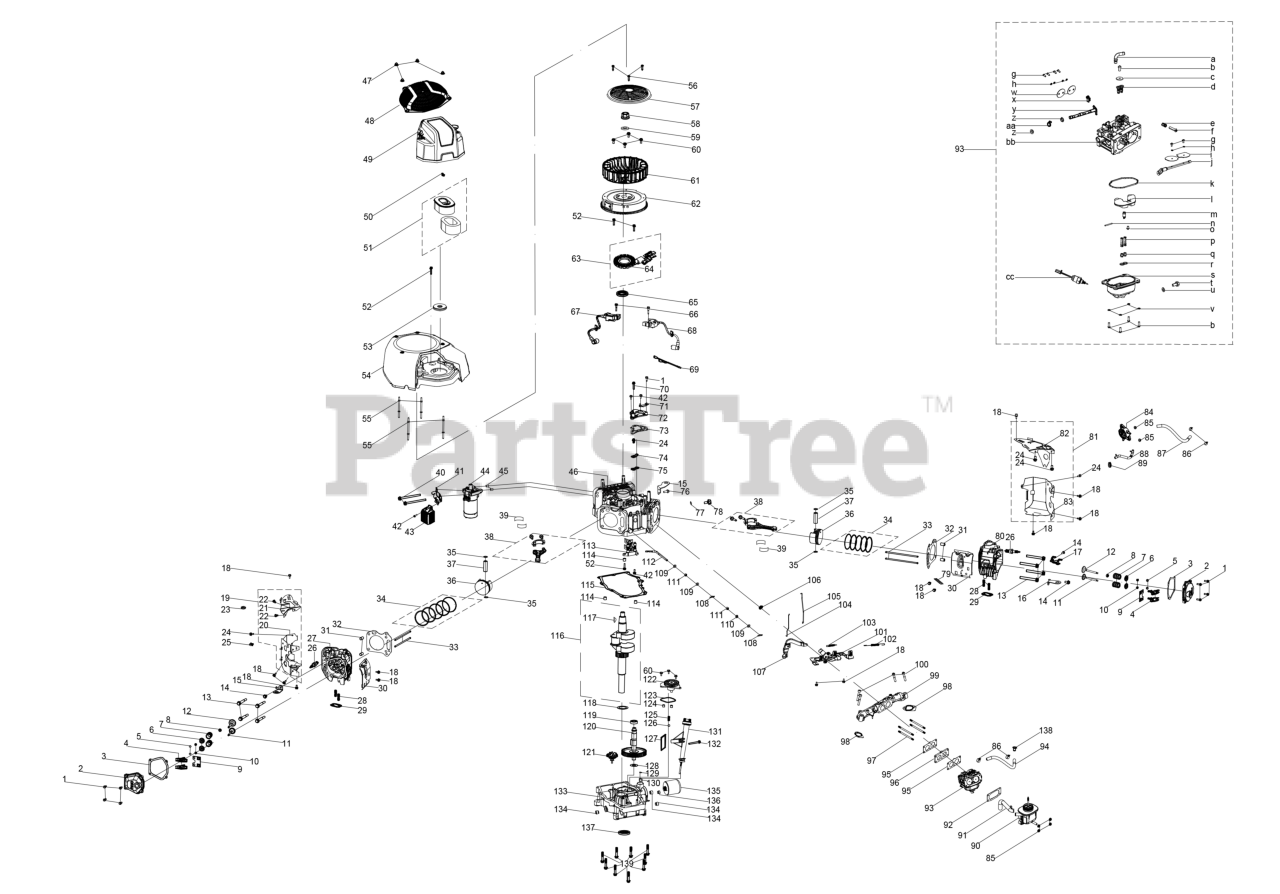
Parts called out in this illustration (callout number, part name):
1	BOLT M6x22
2	VALVE COVER
3	VALVE COVER GASKET
4	ROCKER ARM ASSEMBLY
5	EXHAUST VALVE ADJUSTER
6	VALVE SPRING SEAT
7	VALVE SPRING
8	INTAKE VALVE SEAL
9	PUSH ROD GUIDE
11	EXHAUST VALVE
12	INTAKE VALVE
13	BOLT M10x1.25x87
14	BOLT M8x16
17	MOUNTING BRACKET
18	BOLT M6x12
19	CYLINDER HEAD BAFFLE (LH)
20	CYLINDER HEAD BAFFLE (LH)
21	FLYWHEEL SHROUD (LH)
22	BOLT M6x10
23	HEAT SHIELD GROMMET
24	BOLT M6x10
25	WIRE SUPPORT CLAMP
26	SPARK PLUG (F6RTC/RN11YC/BPR6ES)
27	CYLINDER HEAD (LH)
28	STUD M8 X 34
29	EXHAUST GASKET
31	DOWEL PIN 12x20
32	CYLINDER HEAD GASKET
34	PISTON RIN SET
35	PISTON PIN SNAP RING
36	PISTON ASSEMBLY
37	PISTON PIN
38	CONNECTING ROD
39	CONNETING ROS BEARING
40	BOLT M8x10
41	STARTER RELAY SUPPORT BRACKET
42	BOLT M6x16
44	ELECTRIC STARTER
47	ACORN NUT M6-1
48	SHROUD FAN COVER
49	AIR FILTER COVER ASSEMBLY
50	WING NUT M10
51	AIR FILTER ELEMENT
52	BOLT M6x25
54	BLOWER HOUSING
56	SELF TAPPING BOLT 5.5x25
57	DEBRIS SHIELD
58	NUT M20x1.5
59	WASHER 20.5 x 5 x 40
60	BOLT M6-1 x 18
61	COOLING FAN
63	CHARGING COIL
64	CHARGING COIL
65	OIL SEAL 38 x 58 x 8
66	BOLT M6x30
67	IGNITION MODULE (LH)
68	IGNITION MODULE (RH)
69	CARB HARNESS
70	BOLT M6 X 28
71	FLYWHEEL OUTLET SHIELD
72	BEATHER COVER
73	BREATHER COVER GASKET
74	BREATHER REED BRACKET
75	BREATHER REED ASSEMBLY
76	BOLT M8x20
77	WASHER 20.5X1.5X18
78	BOLT M10x1x10
80	CYLINDER HEAD (RH)
81	CYLINDER SHROUD (RH)
82	COMBINATION GUARD (RH)
83	CYLINDER HEAD BAFFLE (RH)
86	CARBURETOR HOSE CLAMP
90	AIR FILTER BASE
91	BREATHER HOSE
92	AIR FILTER HOUSING GASKET
93	CARBURETOR
94	FUEL LINE 6.3 x 12.5 x 470
95	CARBURETOR GASKET
97	STUD M6-1 X 105
98	INTAKE MANIFOLD GASKET 9Q78
99	INTAKE MANIFOLD
100	BOLT M8x50
101	GOVERNOR GEAR BRACKET
102	GOVERNOR SPRING
103	GOVERNOR SPRING
104	CHOKE LEVER
105	THROTTLE LINKAGE
106	CHOKE LINKAGE LOCK CLAMP
107	GOVERNOR LEVER
108	GOVERNOR SHAFT CLIP
109	FLAT WASHER 8.5X15.8X2
110	GOVERNOR SEAL
111	NEEDLE BEARING 8X12X10
112	GOVERNOR ARM ROD
113	ROCKER ARM ASSMBLY (LOWER)
115	CRANKCASE GASKET
116	CRANKSHAFT ASSEMBLY
117	WOODRUFF KEY
118	WASHER - 38.5X1.0X54
119	CAMSHAFT BEARING
120	CAMSHAFT ASSEMBLY
121	GOVERNOR GEAR
122	OIL PUMP ASSEMBLY
123	OIL PUMP GASKET
125	OIL PUMP SPRING
126	STEEL BALL M9.5
127	OIL PUMP SCREEN
128	THRUST WASHER 17.4X25.9X1.0
129	O-RING 13.2X2.65
130	CRANKCASE OIL PASSAGE PIN
132	BOLT M6x55
133	CRANKCASE COVER
135	ENGINE OIL FILTER
136	OIL FILTER ADAPTER
137	OIL SEAL 38 x 58 x 8
139	BOLT M8x48
